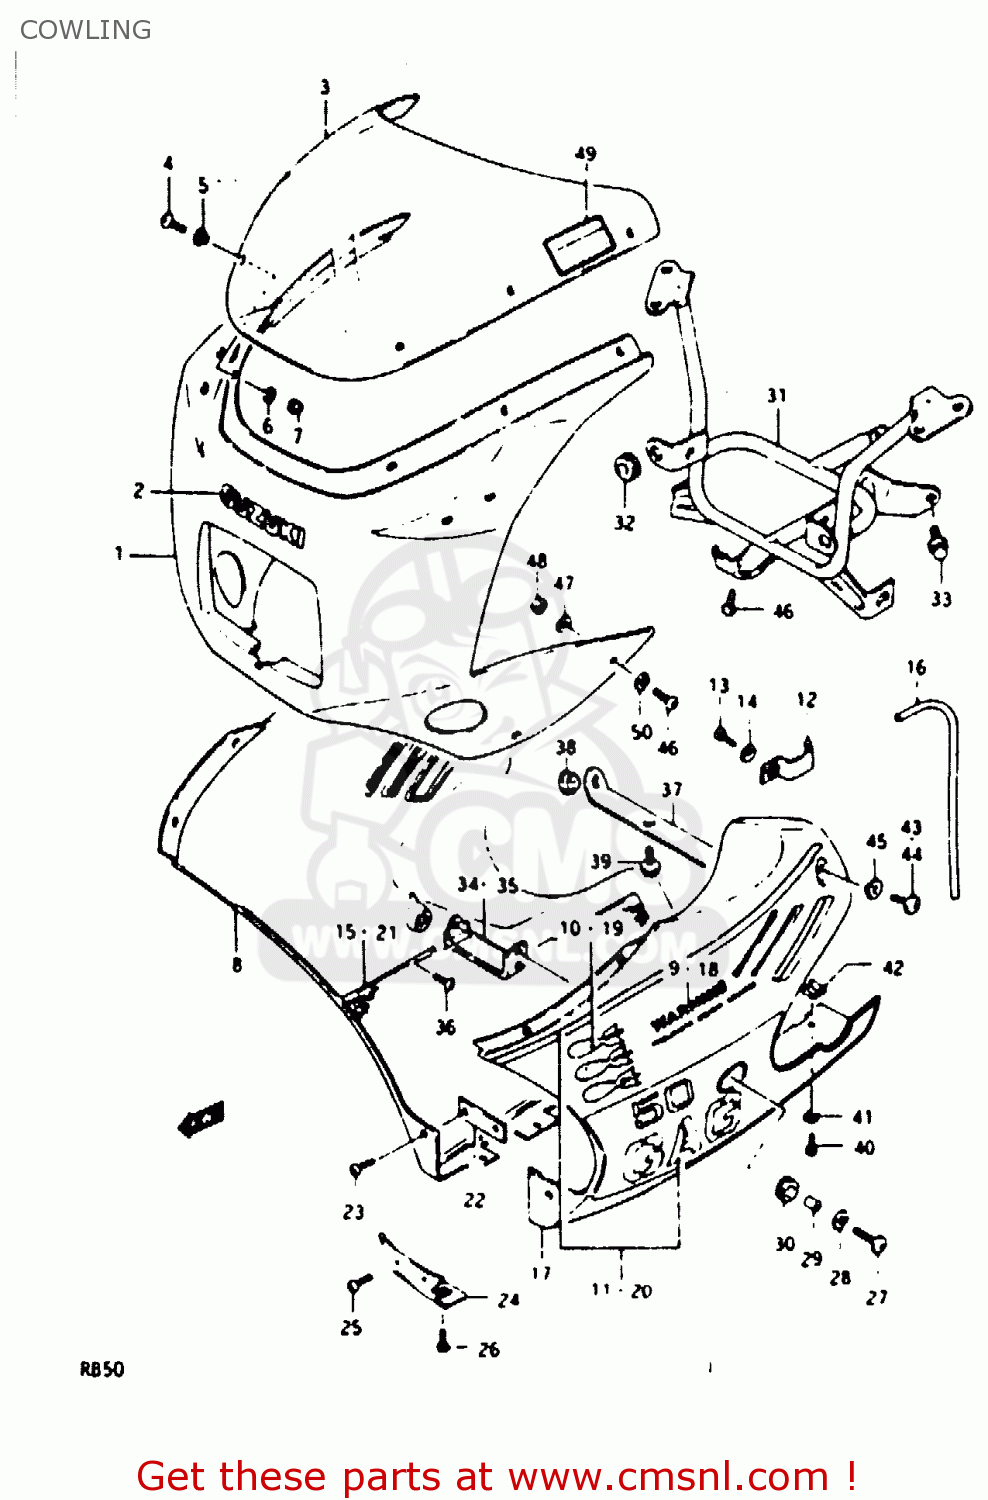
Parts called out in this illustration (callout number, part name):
1	BODY,COWLING
2	EMBLEM
3	WINDOW,COWLING
4	SCREW
5	CUSHION
6	WASHER,5MM
7	NUT 8MM
8	COVER SET,COWLING,R
10	EMBLEM
12	CLAMP
13	SCREW
14	WASHER
15	SHIELD,UNDER COWL HEAT,R
16	HOSE
17	COVER SET,COWLING,L
19	EMBLEM
22	BRACKET,COWLING LWR
23	SCREW
24	BRACKET,COWLING LWR
25	SCREW
26	SCREW
27	SCREW
28	WASHER(6.5X18X1)
29	SPACER (6.1X9X9)
30	CUSHION
31	BRACE,COWLING
32	CUSHION
33	BOLT
34	BRACE,COWLING LWR,R
35	BRACE,COWLING,LOWER,LEFT
36	SCREW
37	PLATE,COWLING SUPPORT
38	CUSHION
39	BOLT
40	SCREW
41	WASHER(5.2X16X1)
42	NUT
43	SCREW 6X12
44	SCREW(6X16)
45	WASHER
46	SCREW
47	WASHER
48	NUT
50	WASHER
